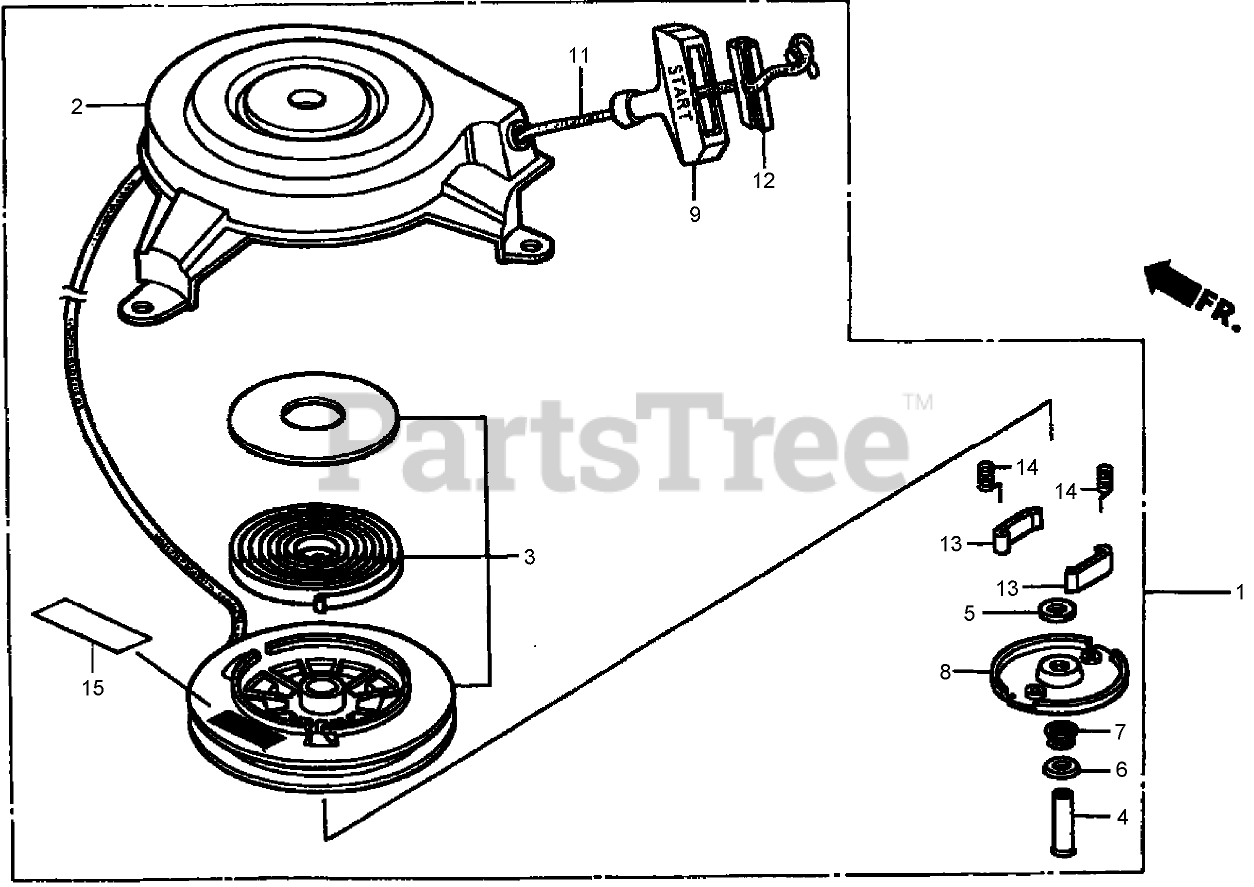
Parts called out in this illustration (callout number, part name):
1	RECOIL STARTER ASM
2	HOUSING ASM
3	PULLEY AND SPRING ASM
4	Pin-Center
5	Plate A-Friction
6	PLATE B-FRICTION
7	Spring-Friction
8	Retainer
9	Handle
11	ROPE (No.4.5X96in)
12	Handle-Reinforcement
13	Ratchet-Starter
14	Spring-Dog
15	MARK-NUMBER, PARTS
